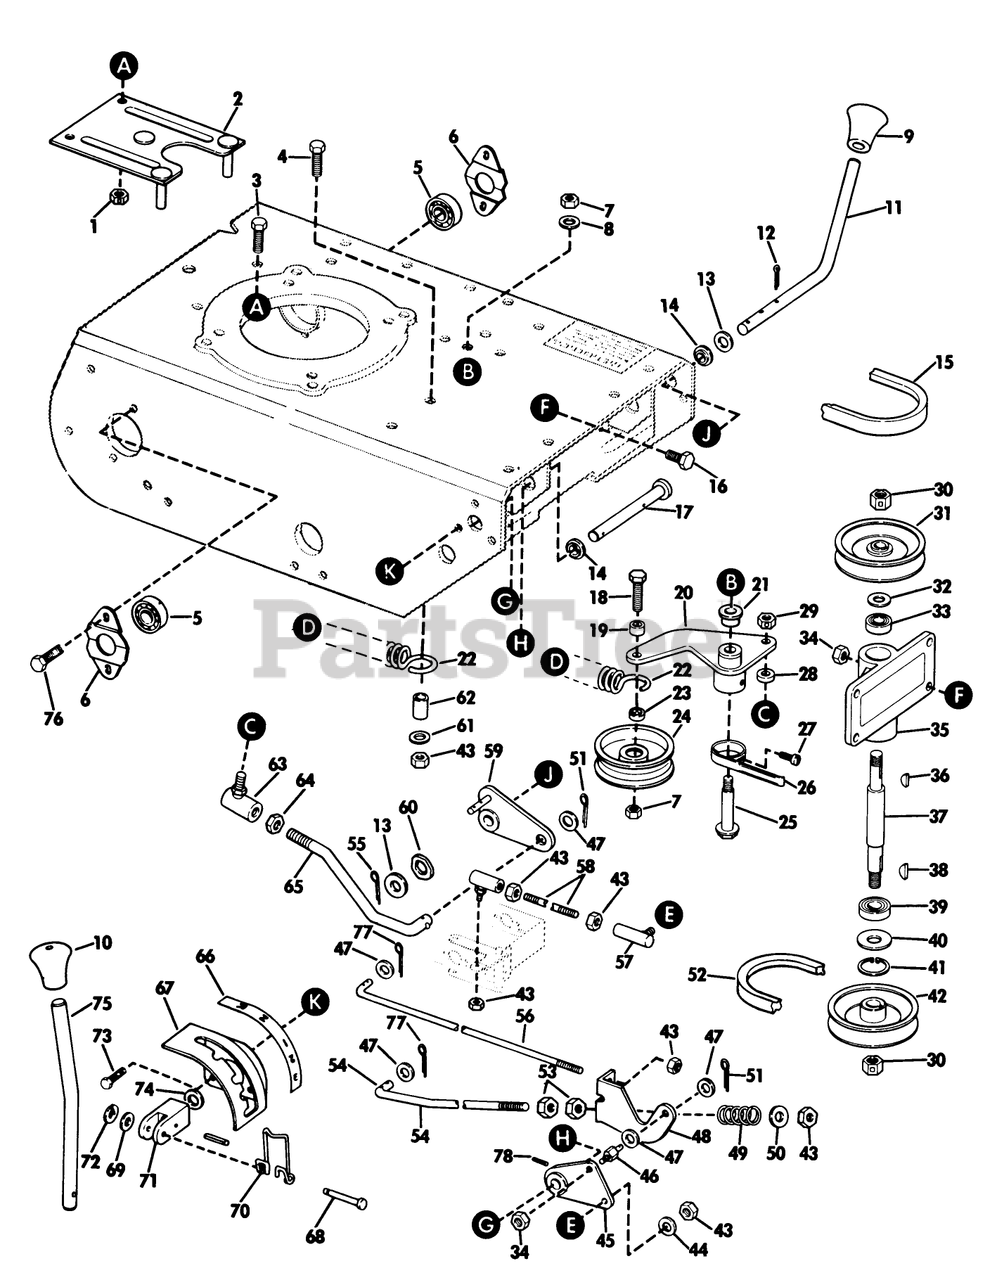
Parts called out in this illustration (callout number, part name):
7	LOCKNUT
12	Cotter Pin
43	STOP NUT
53	STOP NUT
55	Cotter Pin
